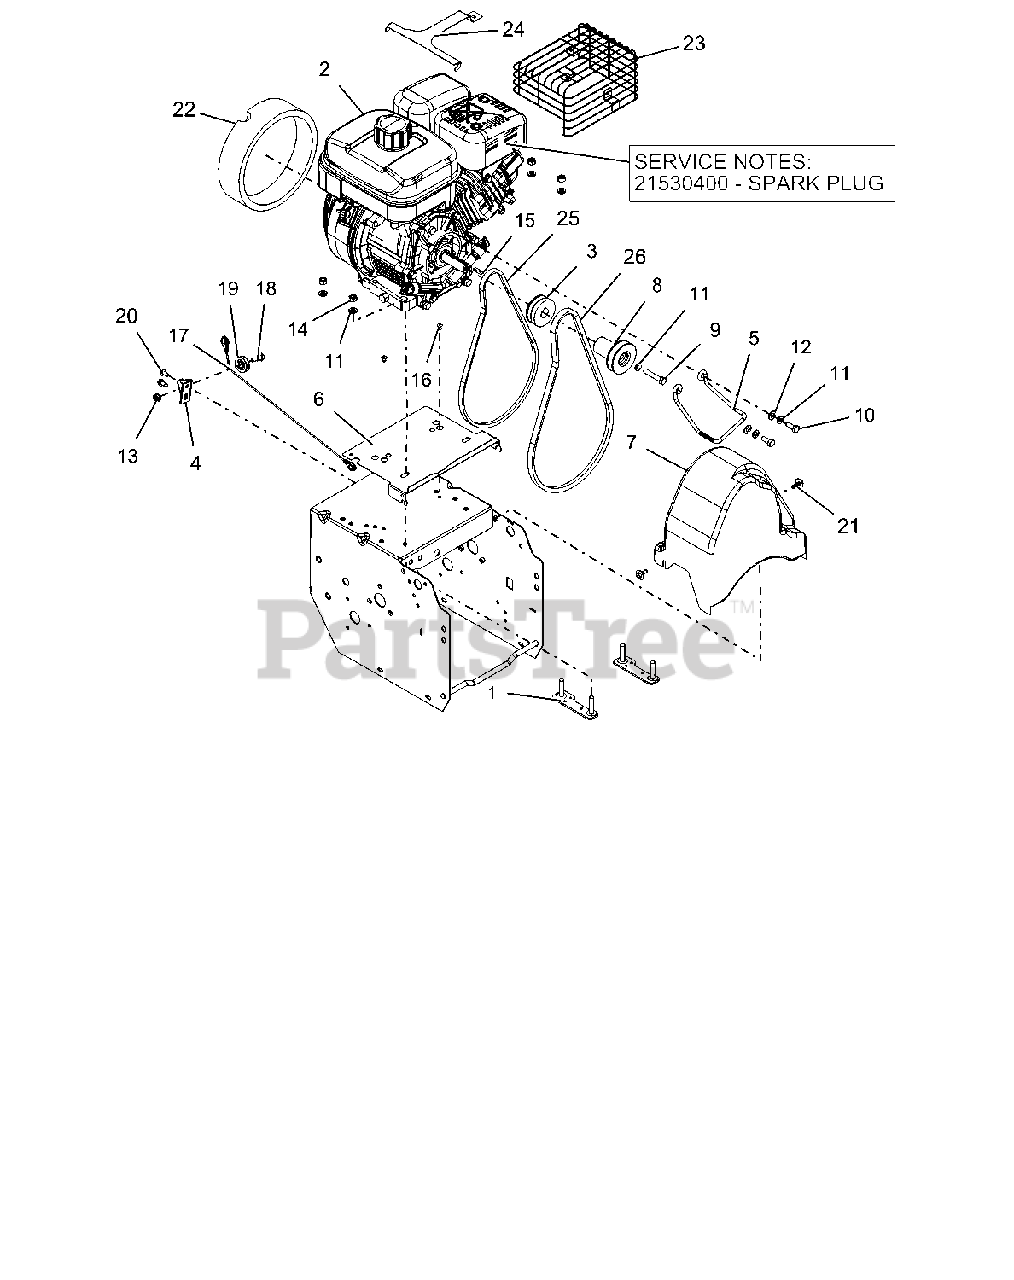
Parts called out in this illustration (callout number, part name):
1	STRAP, ENGINE BOLT-WELDMENT
2	PLUG, SPARK - TEC. SNO-THRO
2	SUBARU EX17 RECOIL ALL-SEASON
3	PULLEY, TRACTION
4	BRACKET, CABLE PULLEY
5	BELT FINGER
6	BAFFLE, COMPACT
7	BELT COVER
8	SHEAVE, AUGER DRIVE
9	@BLT-HEX .31-24X1.75 GR5 YWZC
10	BLT-HEX .31-24X.75 YWZC GR5
11	WSHR-LK .312X.097 HVY YWZC
12	@WSHR-FL-STL.344X.688X.065YWZC
13	@NUT-LK-CTR-FLG .25-20 YWZC
14	@NUT-HEX .31-18 YWZC
15	KEY-SQ .188X.75X.188
16	RVT-POP .187 YZ
17	CABLE, LOWER TRACTION (DELUXE)
18	BOLT, SHLDR-.375X.375X.25-20
19	PULLEY, CABLE
20	SCR-TAP .25-20X.50 HWH TR YWZ
21	SCR-TAP .25-20X.5 CAPTIVE
22	FOAM COVER, RECOIL-SUBARU
23	GUARD,MUFFLER,SUB 20A-37303-11
24	GUARD, SNOW-SUBARU EX17
25	V-BELT, 3L-WRAPPED
26	V-BELT, HA-RAW EDGE
